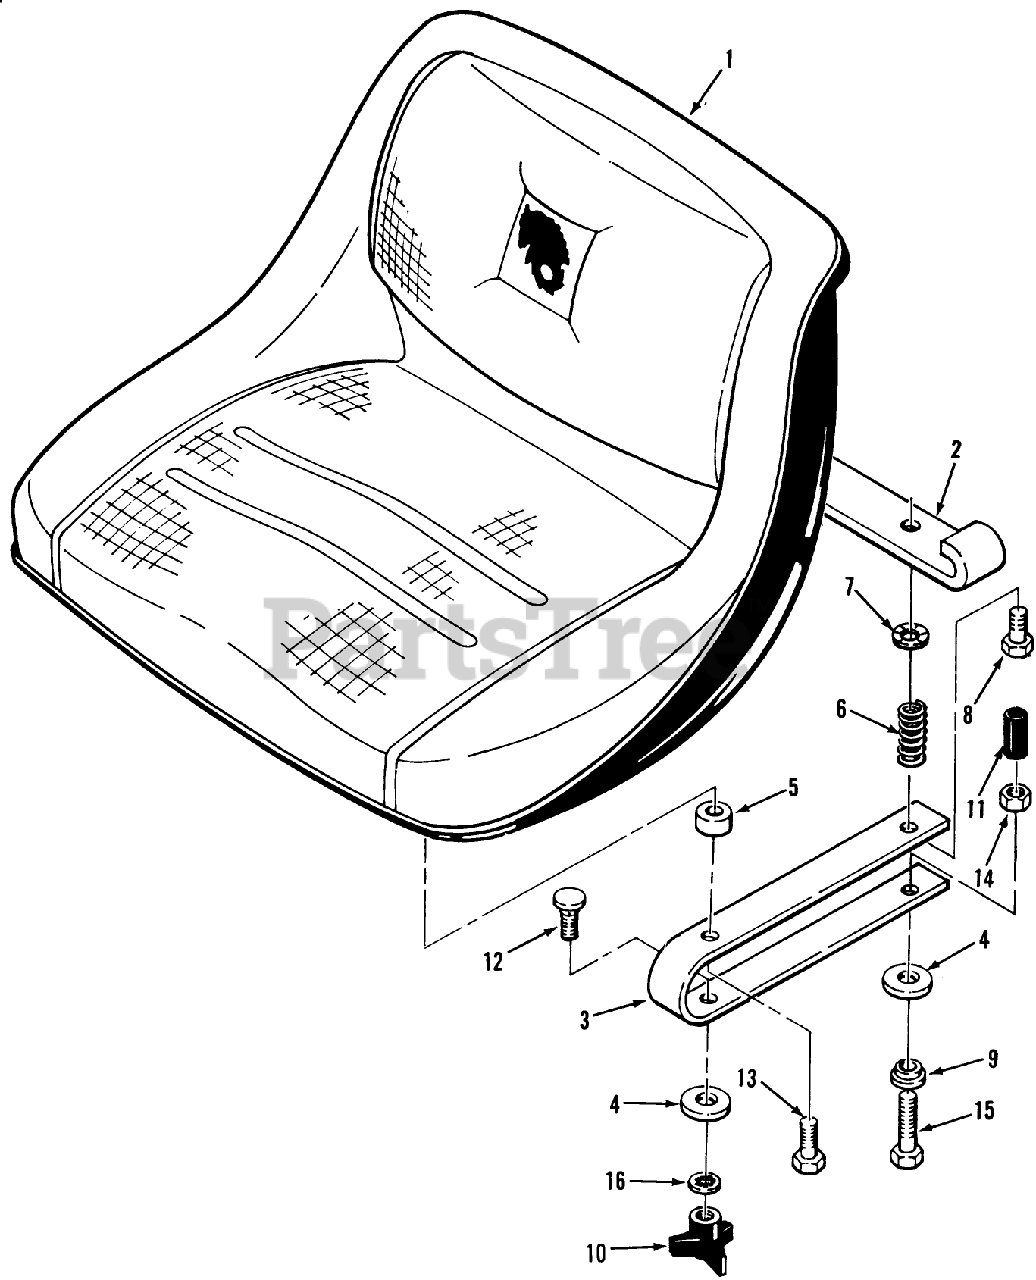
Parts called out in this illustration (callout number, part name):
1	Seat
2	PLATE SEAT SWITCH B
3	Seat Spring
4	WASHER
5	GROMMET-RUBBER
6	SPRING COMPRESSION
7	NUT-PUSH
8	Special Bolt
9	BUSHING
10	Knob
12	Bolt-Carriage
13	Bolt
14	Nut
15	Full Thread Bolt 5/16 x 1-1/2
16	Washer-Lock
